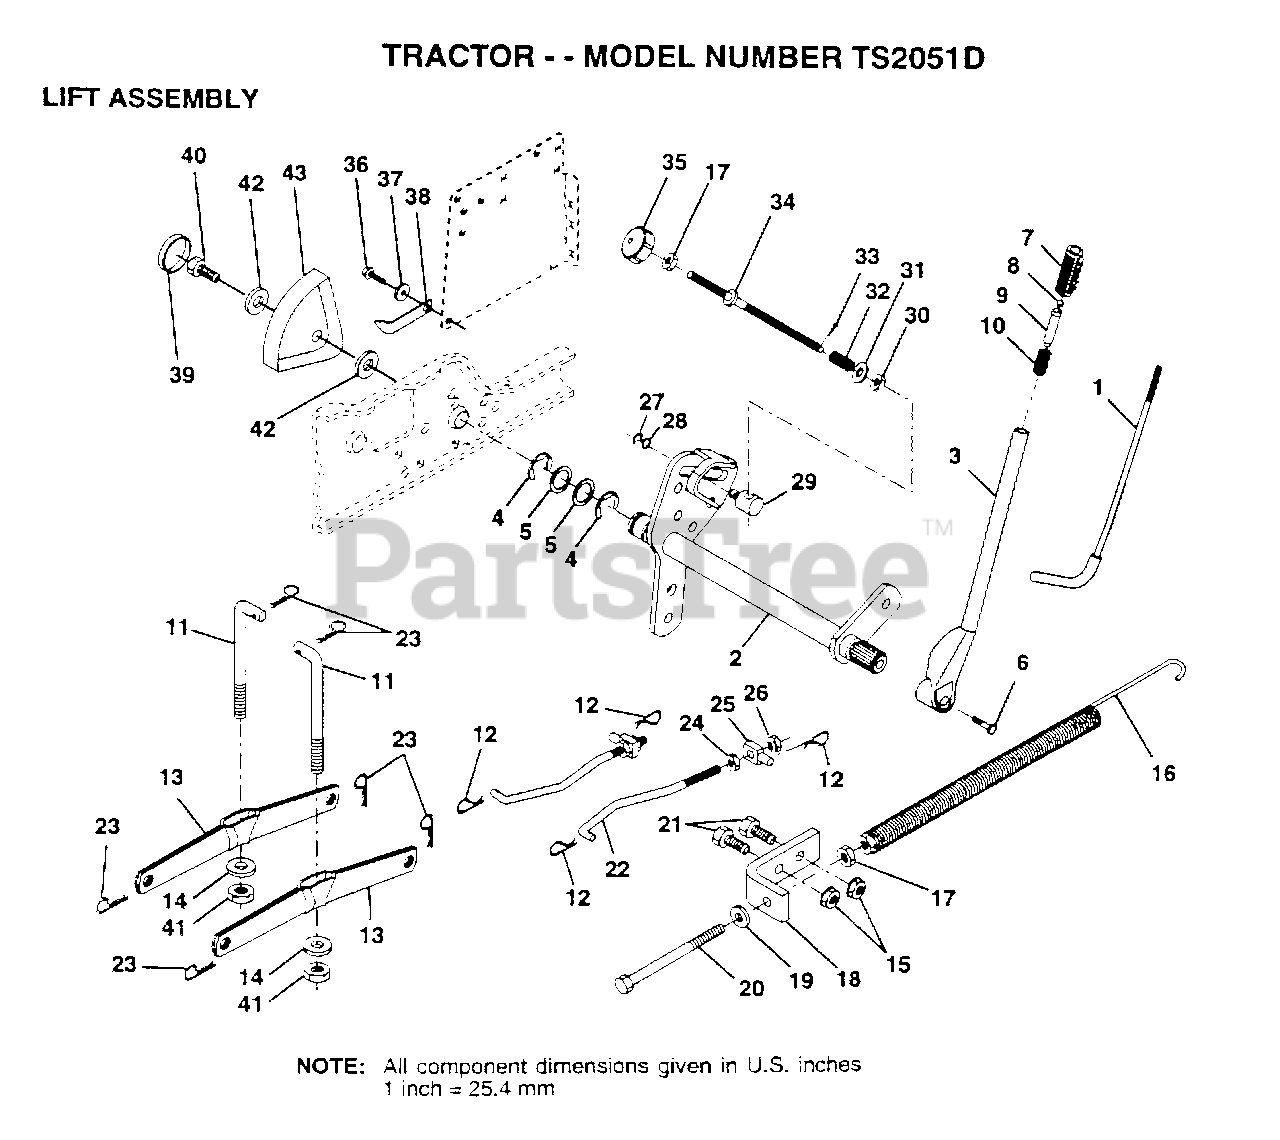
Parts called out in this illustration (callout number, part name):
1	LEVER ROD LT
4	E-RING
5	WASHER
6	"BOLT,HEX"
7	GRIP HANDLE
10	SPRING T
12	RETAINER.SPRING
13	ARM SUSP REAR
14	BEARING PVT LH
17	NUT
18	BRACKET SPRING AS
19	WASHER
20	BOLT-ADJ SPRING T
21	BOLT
22	LINK.FRONT
24	NUT
25	TRUNION
26	NUT.LK.W/WSH.1/2.
27	KLIP RING
28	WASHER
29	TRUNION LT
30	NUT T
31	WASHER
32	SPRING.COMP.INF.H
34	ROD.ADJ.LIFT
35	KNOB INF 3/8-16
36	SCREW
37	WASHER T
38	POINTER HGT IND
39	"PLUG,HOLE"
40	SCREW
41	NUT.CROWNLOCK.3/8
42	WASHER
43	HEIGHT INDICATOR
